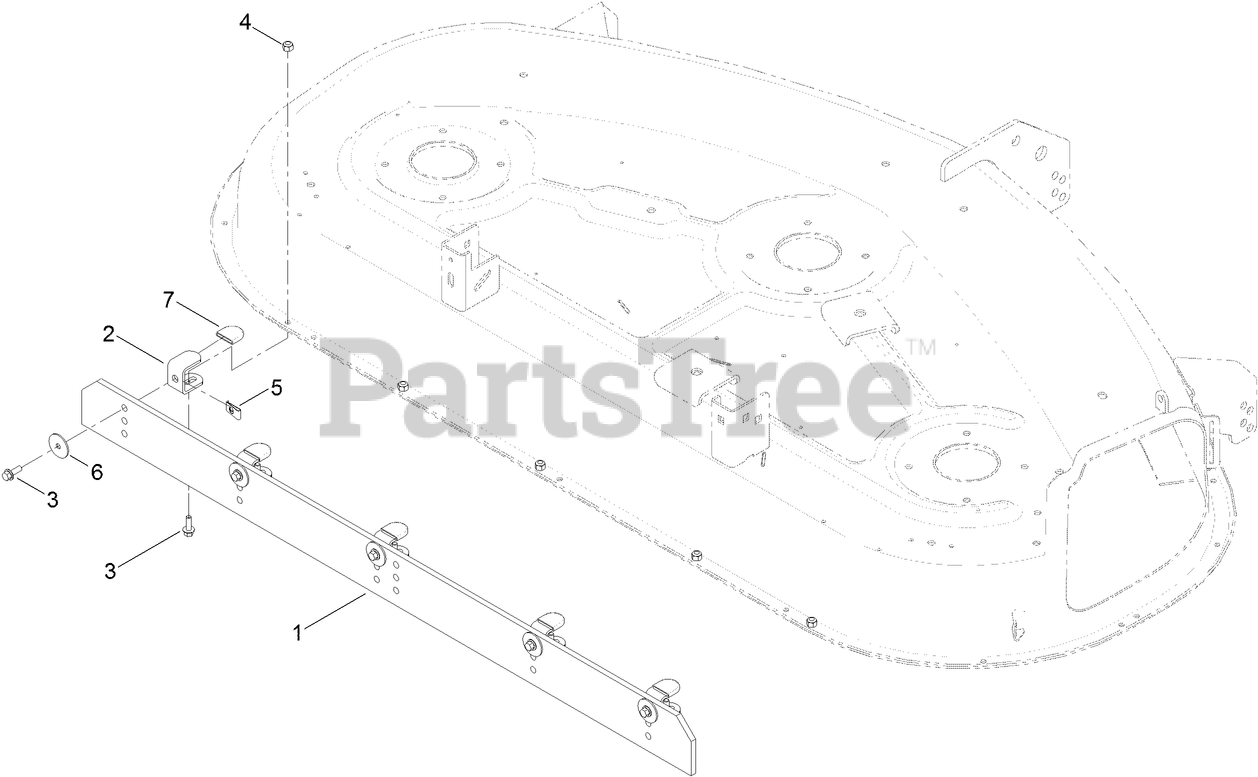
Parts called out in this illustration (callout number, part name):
1	WIPER-54 INCH
2	BRACKET-MOUNTING
3	SCREW-HHF
4	NUT-LOCK, NI
5	NUT-SPEED
6	WASHER-FLAT
